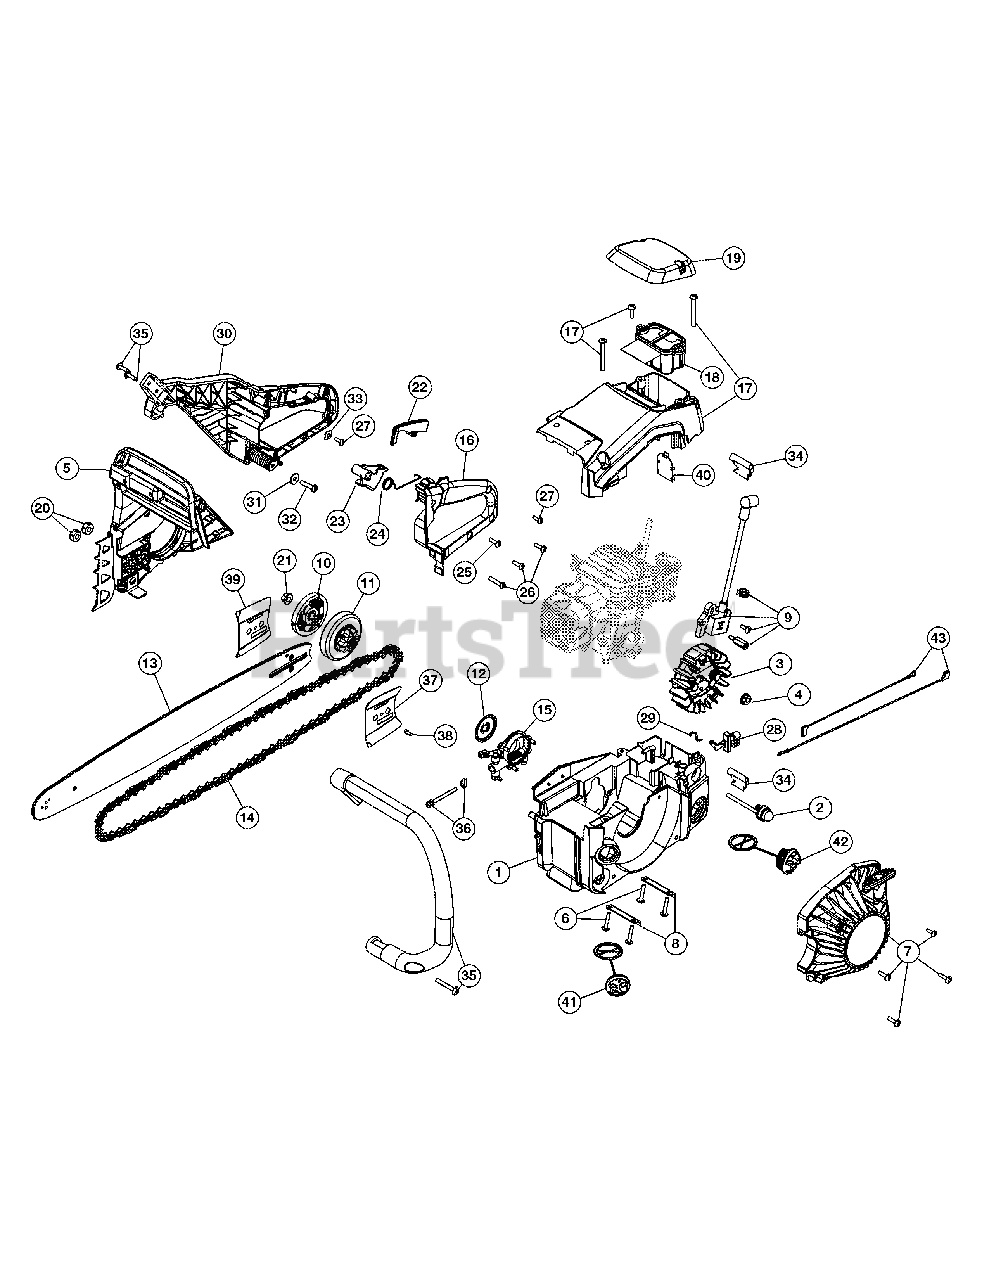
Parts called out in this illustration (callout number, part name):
1	Housing Assy
2	Primer Bulb W/Line
3	Flywheel Asm
4	Flywheel Nut
5	Chain Brake Asm
6	Engine Mnt Hdw
7	Starter Hsg Asm
8	Engine Mnt Plate Flg
9	Module 55Cc
10	Clutch Assy 55Cc
11	Clutch Drum
12	Shield Oil Pump
13	Bar 51Cc Saw 18"
14	Chain 18" 55Cc
15	Oil Pump Asm 55Cc
16	Cover Assy Rr Saw
17	Cover Assy Top
18	Aircleaner Assy
19	Aircleaner Cover
21	Clutch Hdw
22	Trigger Release
24	Trigger Spring
25	Upper Grip Screw
26	Screw 8/16X.625
27	Screw 8/16X.500
30	Handle Assy Rr
32	Srew Anti Vibe
34	Boot: Carb Saw
35	Handle Assy 55Cc
36	Tension Screw/Nut
37	Guide Plate Inr
38	Screw 6/19-.375
39	Guide Plate Otr
42	Fuel Cap Saw
43	Ground Wire
